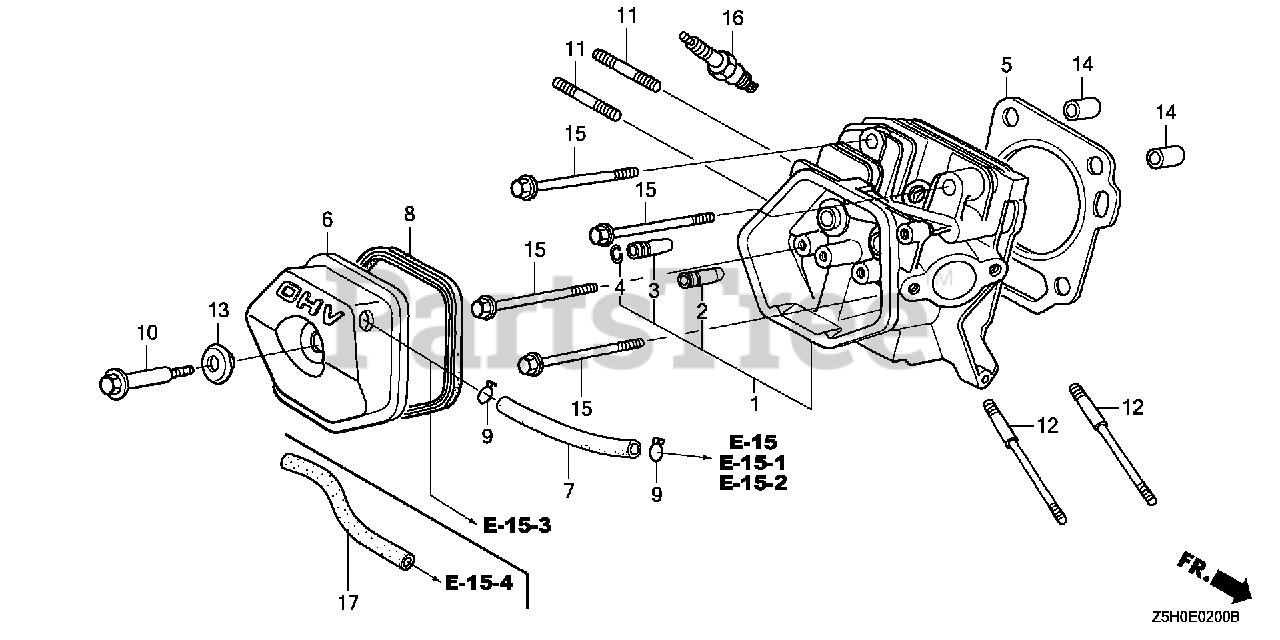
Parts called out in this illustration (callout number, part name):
1	CYLINDER HEAD
2	GUIDE, VALVE (OS)
3	GUIDE, EX. VALVE (OS)
4	CLIP, VALVE GUIDE
5	GASKET, CYLINDER HEAD
6	COVER, HEAD
7	BULK HOSE, VACUUM (11X1000) (Honda Code 4537312). (11X105)
8	GASKET, CYLINDER HEAD COVER
10	BOLT, HEAD COVER
11	BOLT 2, STUD (8X32)
12	BOLT, STUD (8X123)
13	WASHER, HEAD COVER
14	PIN A, DOWEL (12X20)
15	BOLT, FLANGE (10X80)
16	SPARK PLUG (BPR5ES) (NGK)
16	SPARK PLUG (W16EPR-U) (DENSO)
16	SPARK PLUG (BPR6ES) (NGK)
16	SPARK PLUG (W20EPR-U) (DENSO)
